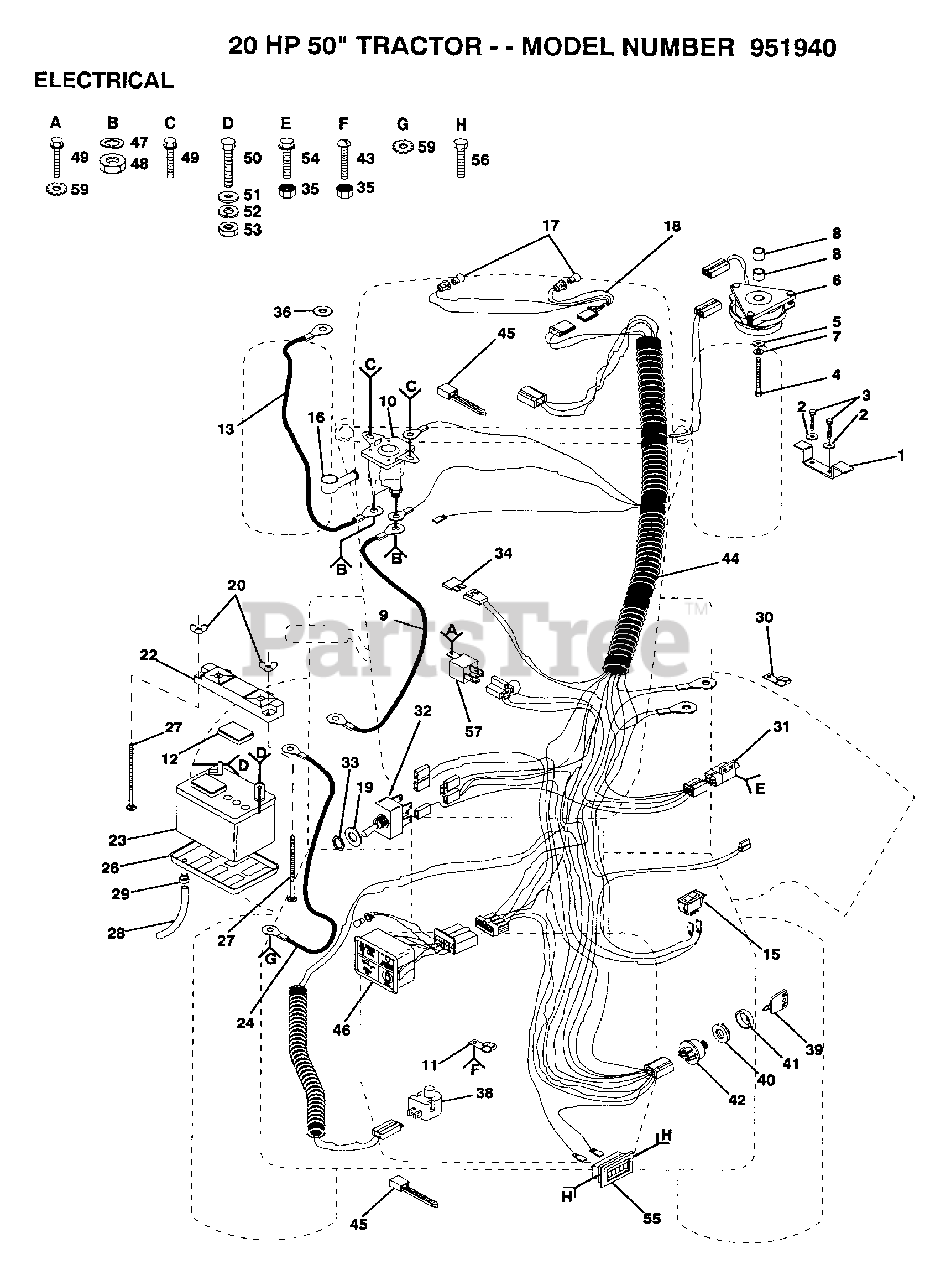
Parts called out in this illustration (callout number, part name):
2	LOCKWASHER
3	BOLT
5	WASHER
7	LOCKWASHER
8	SPACER-CLUTCH
9	CABLE-BATTERY T
12	"CAP,BATTERY "
13	"CABLE,STARTER T"
15	SWITCH LT
17	HEADLAMP BULB
18	"HARNESS,LIGHT SOC"
24	CABLE T
26	"TRAY T, BATTERY"
27	BOLT
28	"DRAIN TU T, BATT"
29	HOSE CLAMP T
30	CLIP GTV
31	SWITCH INTERLOCKT
33	HEX NUT T
34	FUSE HYT
35	"NUT,KEPS"
36	LOCKWASHER
38	SWITCH SEAT
39	KEY
40	NUT IGNITION
44	HARNESS.IGN
45	WIRE TIE
46	LIGHT.PKG.ASM.
48	NUT
49	SCREW ST
50	BOLT LT
51	WASHER
52	LOCKWASHER
54	SCREW
55	HOUR METER T
56	SCREW
57	RELAY ASSY T
59	LOCKWASHER
